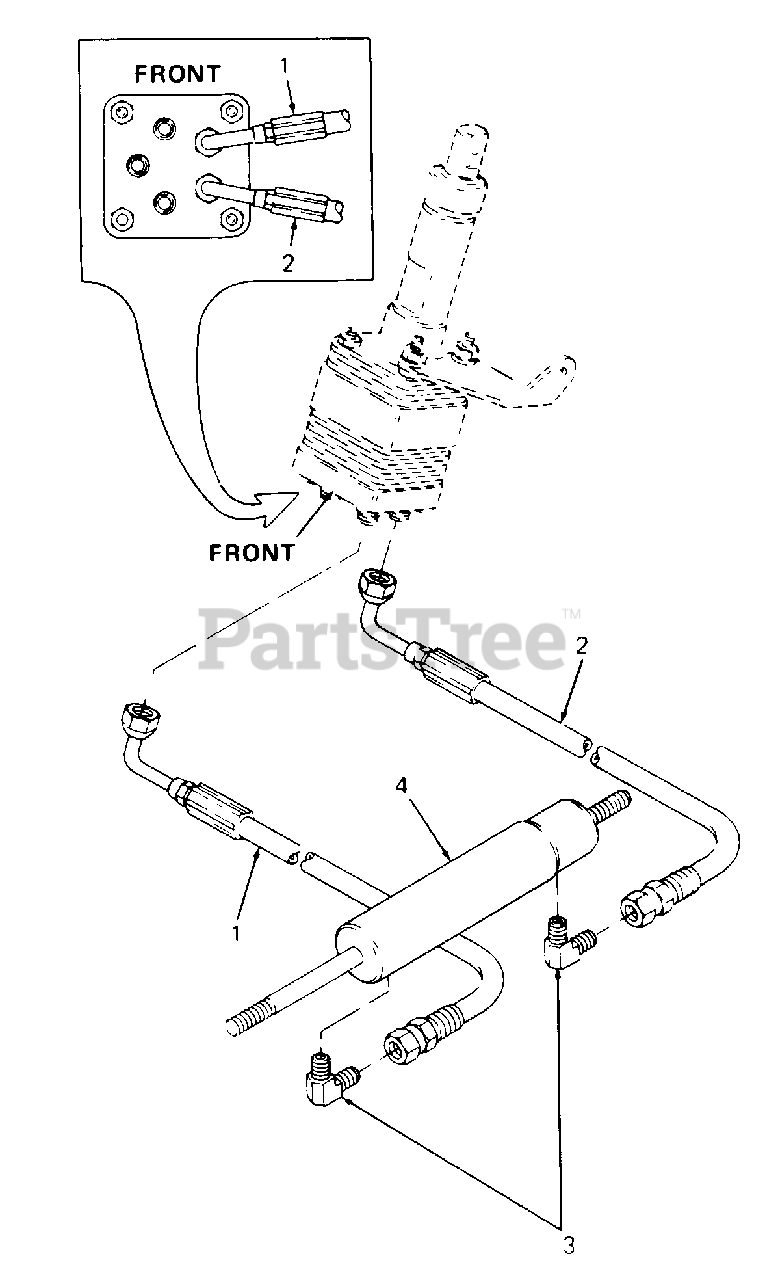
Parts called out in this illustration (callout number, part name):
1	Hose, Steering, 10.5 Lg
2	Hose, Steering, 8.9 Lg
3	Elbow, 90 Deg Tube
